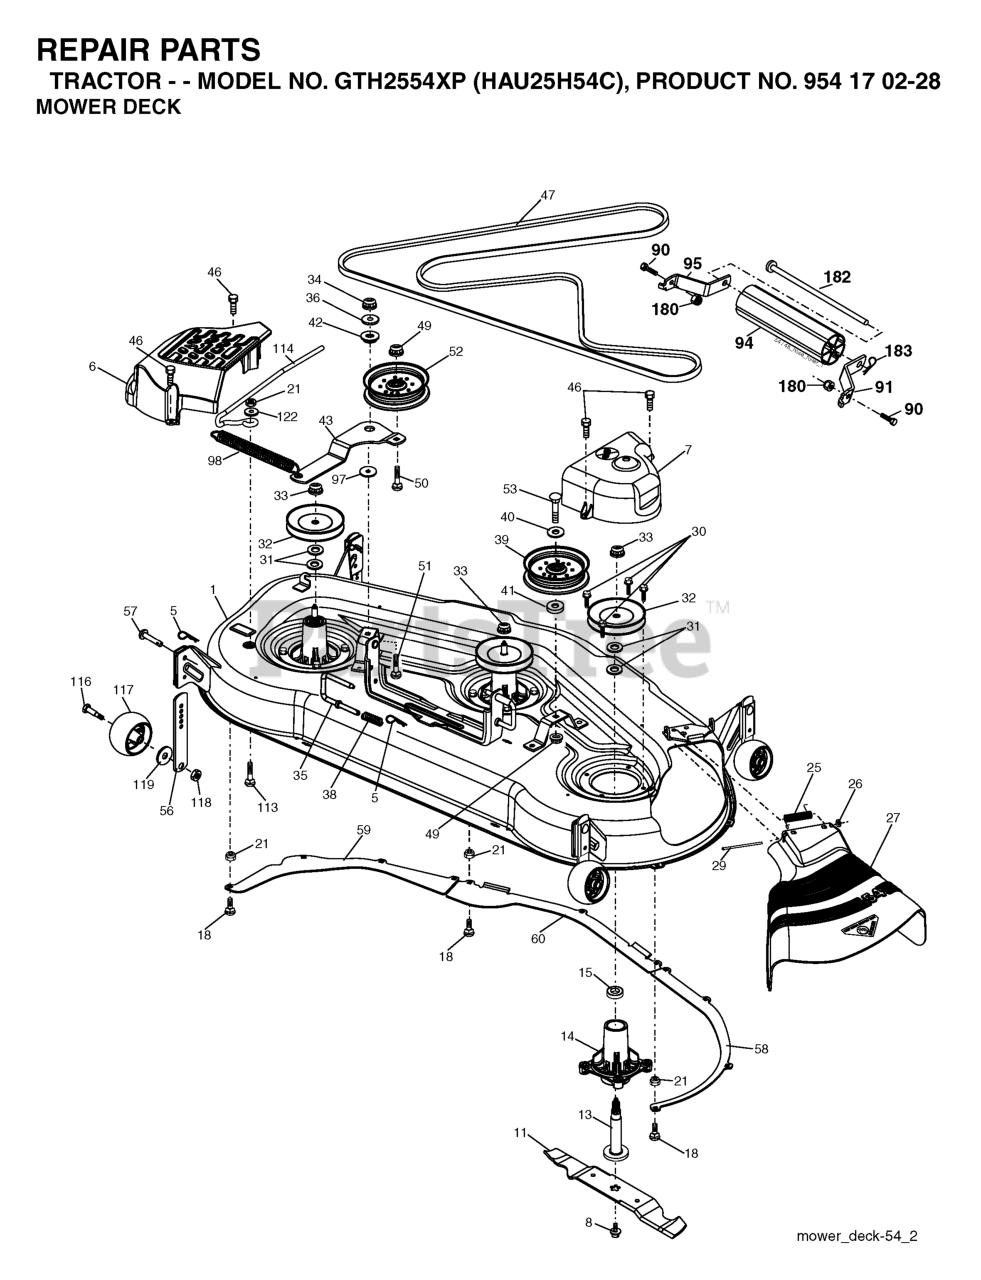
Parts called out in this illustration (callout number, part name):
1	DECK.PNT.WLDMENT.54"
5	RETAINER-SPRNG RB
6	COVER.MANDREL.LH.DECK.54"
7	COVER.MANDREL.RH.DECK.54"
8	BOLT 7/16 ASM BLADE
11	48" Hi-lift Blade
13	SHAFT ASM MANDREL
14	RP.HOUSING.MANDREL.4PT.
17	BOLT.CARR.5/16-18X5/8.SHORT
21	LOCKNUT
25	SPRING, TORSION
26	NUT PUSH M
27	DEFLECTOR
29	ROD.HINGE
30	SCREW, WASHER HEAD
31	WASHER.SPACER.MANDREL
32	PULLEY, MANDREL
33	NUT, FLG TOPLOCK 9/16"
35	PIN.SUSPENSION.REAR.54"
36	WASHER
38	SPRING COMPRESSION PULL
39	PULLEY.IDLER.STATIONARY
40	WASHER
41	Washer 13/32 x 1-3/8 x 13 Ga.
42	SPACER.RETAINER.MOWER
43	ARM.IDLER.54"
46	SCREW.1/4-20X5/8
47	V-BELT 54" HIGH PERFORMANCE
49	NUT LOCK FLG 3/8-16 UNC
51	BOLT
52	IDLER PULLEY
53	BOLT.HEX
56	BAR.ADJUST.WHEEL.ANTI.SCALP.BL
57	RIVET.PIN.HEAD.YELLOW.
58	BAFFLE.RIGHT.54"
59	BAFFLE.LEFT.54"
60	BAFFLE CENTER 54" MOWER
90	BOLT RB
91	BRKT.NOSEROLLER.RH.48"
94	NOSE ROLLER 48"
95	BRKT.NOSEROLLER.LH.48"
97	WASHER 12/32X2X10GA
98	SPRING.CLUTCH.DRIVE.54
114	ROD TENSION RELIEF
116	SHOULDER BOLT
117	WHEEL GAGE DONUT
118	LOCKNUT
119	WASHER.5/16.FLAT.STE.STD.
122	BUSHING.RELIEF.TENSION
180	NUT.71038.31-18.HEX.NYLOCK
182	ROD.ROLLER.NOSE.NARROW.48"
183	SPRING RETAINER
